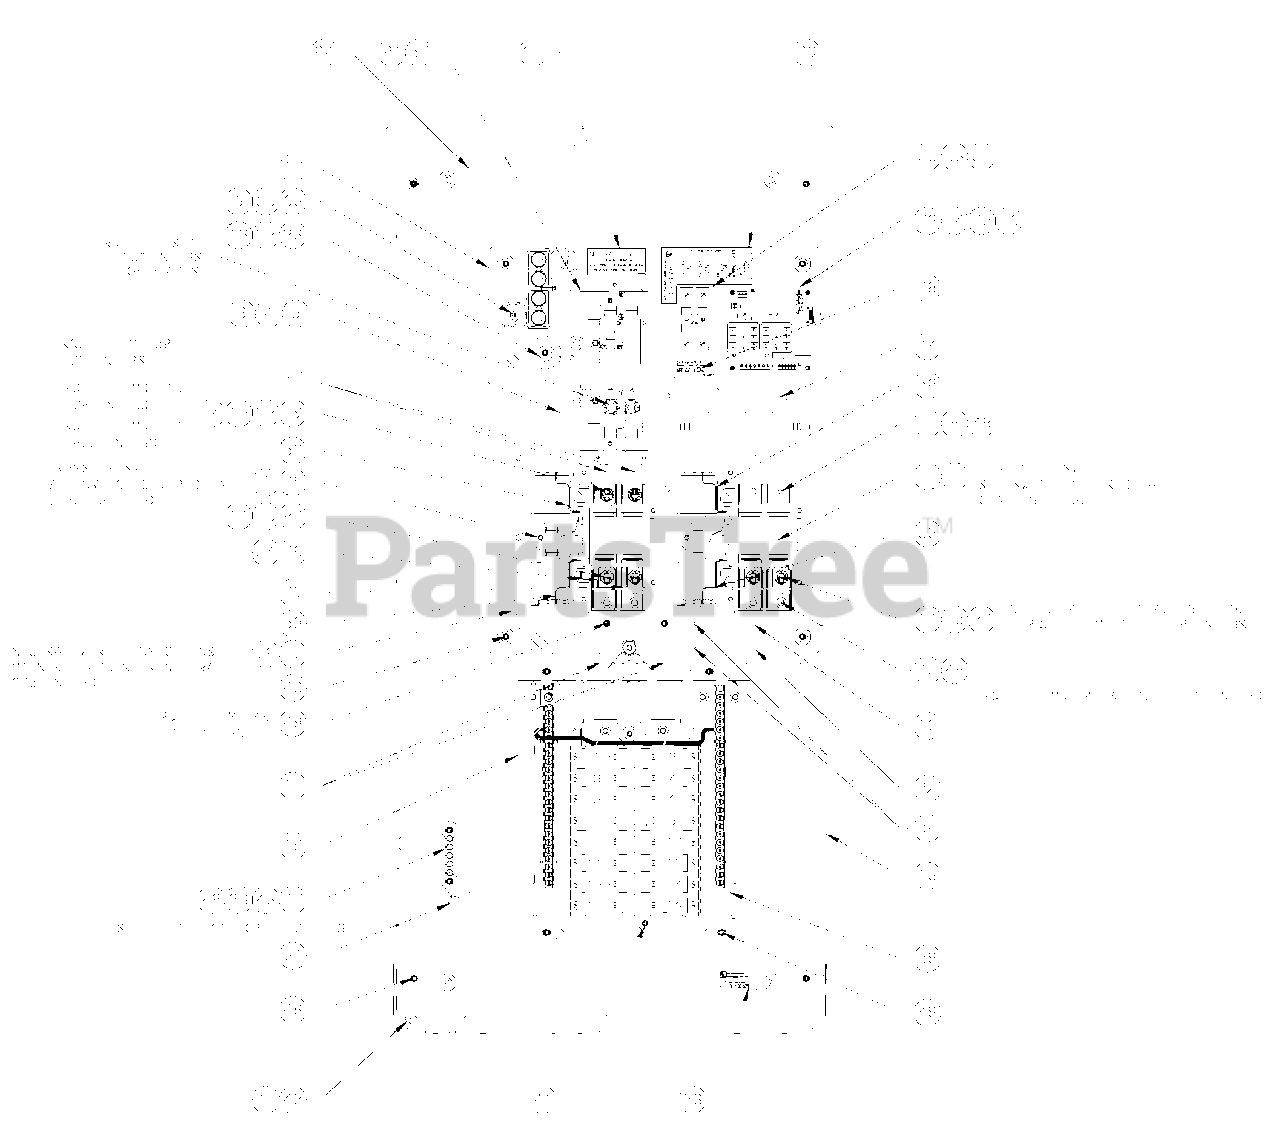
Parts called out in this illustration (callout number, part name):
1	TRANSFER SW. HSB 200A 2P 250V
2	SCREW HHTT M5-0.8 X 10 BP
3	CB 0200A 2P 240V S QN2 LL
4	BASE, QN CIRCUIT BREAKER
5	SCREW PPHM #8-32 X 1/2
6	SCREW HHTT #8-32 X 1/4 CZ
7	SPACER 200 AMP TRANSFER
8	BOLT CARR 1/4-20 X 1"
9	BUSBAR, 200A TRANSFER SW T1
10	BUSBAR, 200A TRANSFER SW T2
11	WIRE, 3/0 N1,N2
12	BUSBAR, PANELBOARD INTERCONNECTION
13	WIRE, NEUTRAL BONDING 6AWG
14	LUG SOLDERLESS 250-#6 AL/CU
15	SCREW BHSC 1/4-20 X 3/8
16	ENCLOSURE,LOAD SHED TRANSFER SWITCH`
17	SUBPLATE, PANELBOARD
18	SUBPLATE, LOADCENTER
21	CB BRKT 200A TRANSFER SWITCH SIEM
22	WASHER LOCK M6-1/4
23	NUT HEX 1/4-20 SS
24	DECAL, TRANSFER SWITCH DATA
27	DECAL, NEUTRAL CONNECTION
28	DECAL, FUSE REPLACEMENT
29	DECAL, CUSTOMER CONNECTION
31	DECAL, GROUNDING LUG
33	DECAL, UL PANELBOARD
41	SCREW HHTT M5-0.8 X 16
42	NUT TRIC 1/4-20 X .525
43	THUMB SCREW 1/4-20x1/2
44	BATTERY CHARGER ASSEMBLY
45	SCREW BHSC 1/4-20 X 3/4
46	GROUND BAR (5) 2-14 AWG CONN
47	WASHER SHAKEPROOF EXT 1/4 STL
48	NUT HEX FL WHIZ 1/4-20
55	FUSEBLOCK 30A 600V 2 POLE
56	FUSE 5A X BUSS HLDR73591
57	SCREW HHTT M4-0.7 X 10 BP
58	16 CIR L/CENTR 200A/240V SIEMS
65	ASSY-NEUT BLK 200-400A W/TAP
66	SCREW HHTT M6-1.0 X 12 MM
72	NEUTRAL WIRE
73	ASSY PCB 2008HSB LOAD SHEDCTRL
74	RELAY SOC 12VDC DPDT 10A@240VA
75	SPACER .20 X .375 X .375 PL
76	NUT HEX FL WHIZ M5-0.8
77	TIE-WRAP MOUNT(FIR TREE SYTLE)
79	STRAIGHT SPADE CONNECTOR
